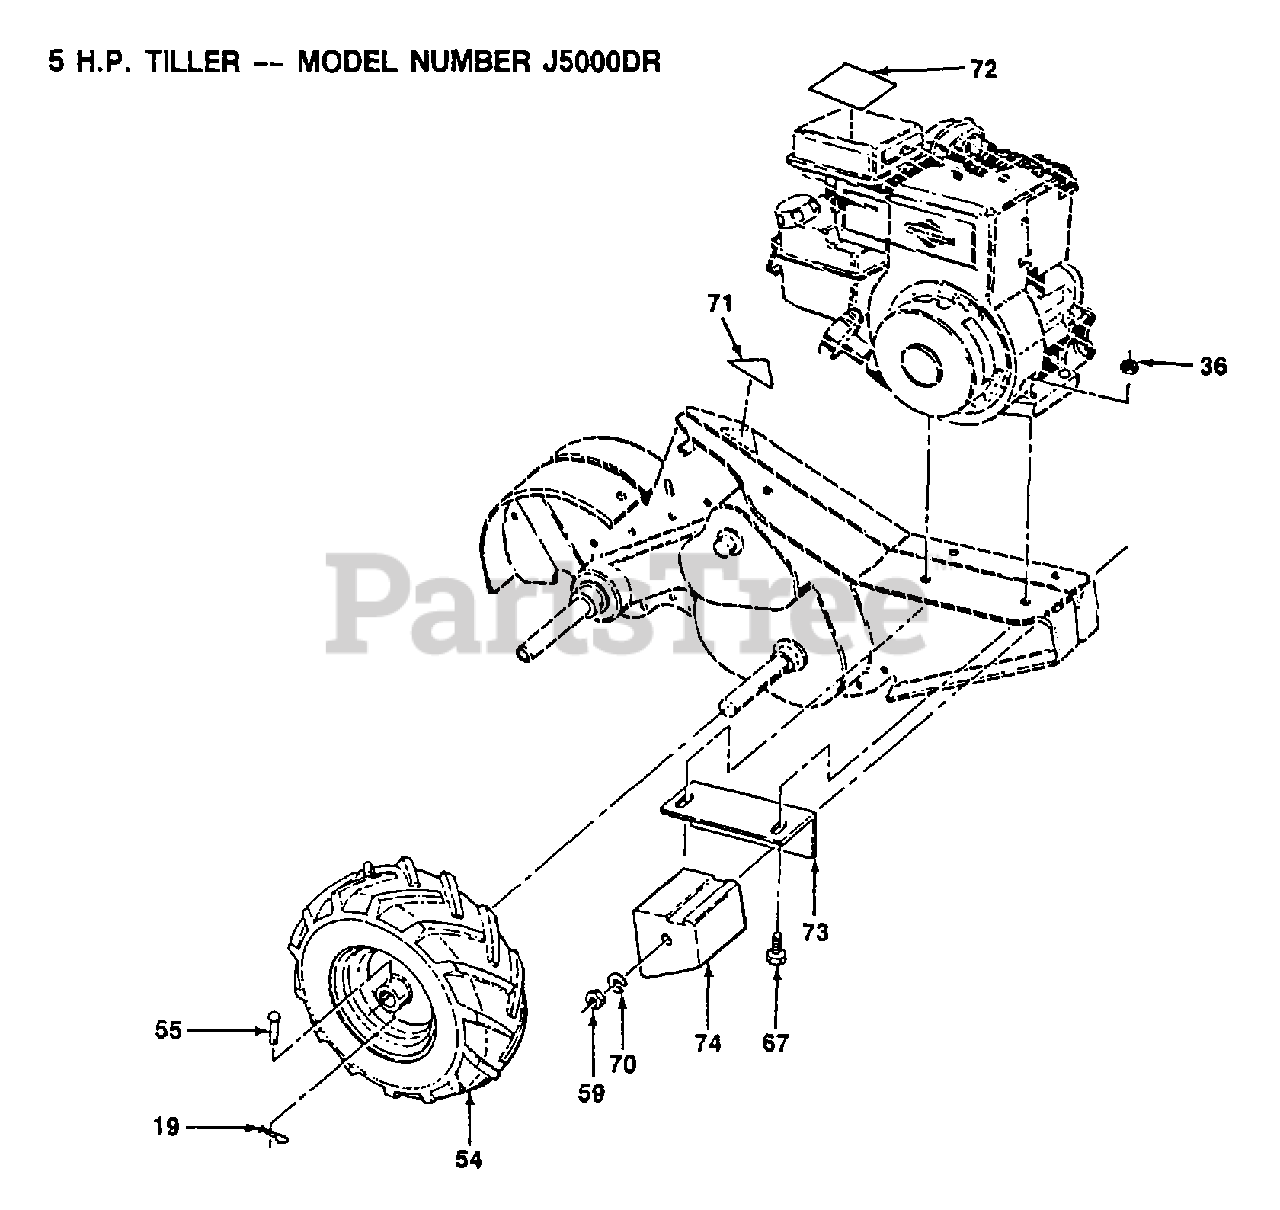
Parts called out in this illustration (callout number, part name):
72	DECAL TI
73	BRACKET RH CRT
74	COUNTERWEIGHT CRT
